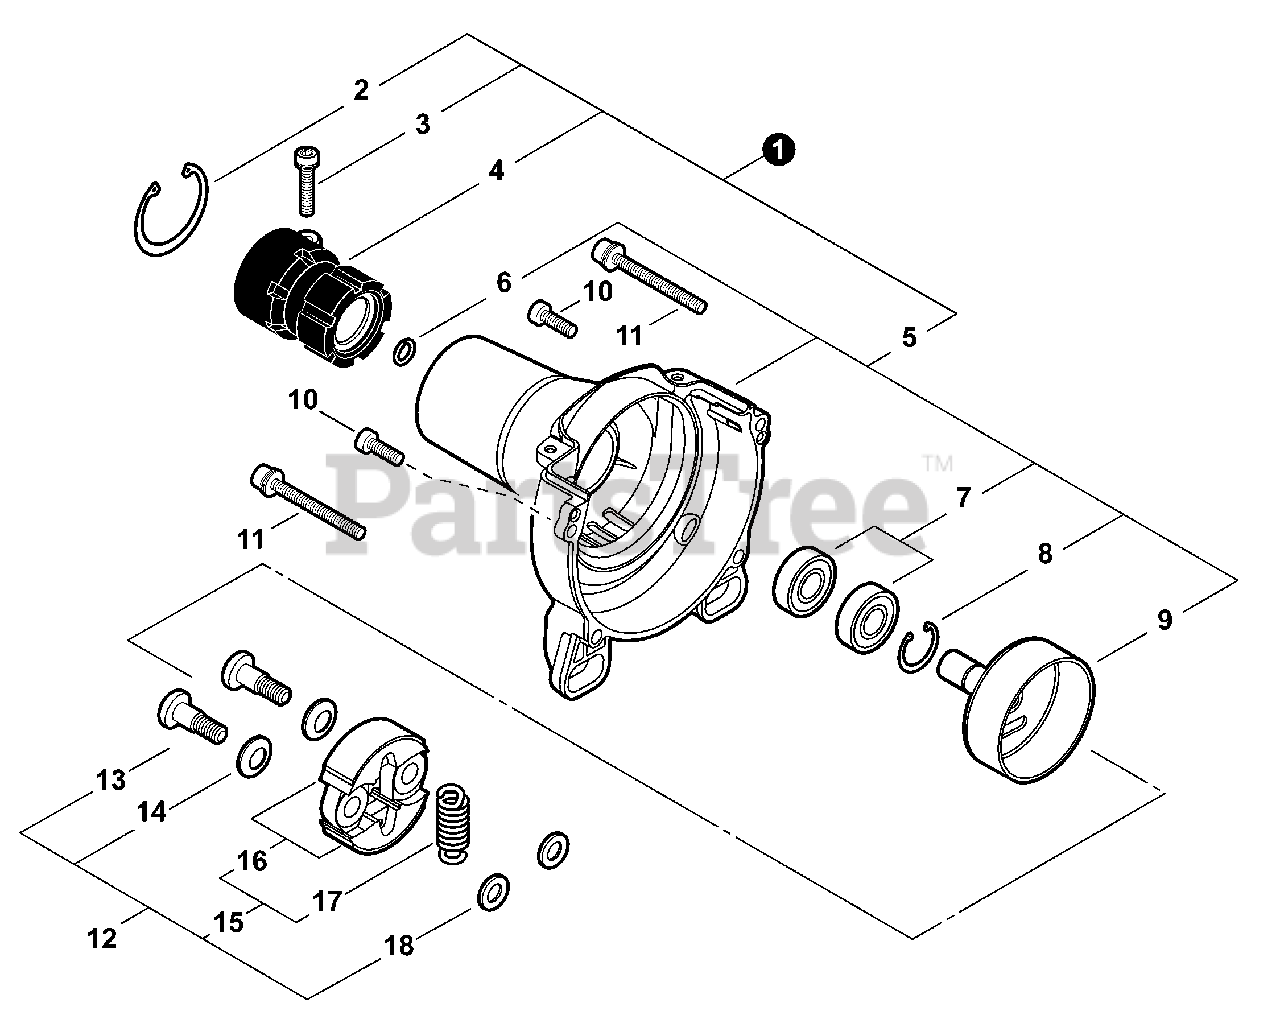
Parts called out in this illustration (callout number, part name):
1	COVER ASSY, FAN
2	RING, SNAP 40
3	BOLT M5×22
4	CUSHION, AV
5	COVER KIT, FAN
6	RING, SNAP 10
7	BEARING, BALL 6000ZZ
8	RING, SNAP 26
9	DRUM, CLUTCH
10	BOLT M5×16
11	BOLT M5×45
12	CLUTCH ASSY
13	BOLT, CLUTCH
14	WASHER, SPRING
15	SHOE ASSY, CLUTCH
16	SHOE, CLUTCH
17	SPRING, CLUTCH
18	WASHER 6MM
